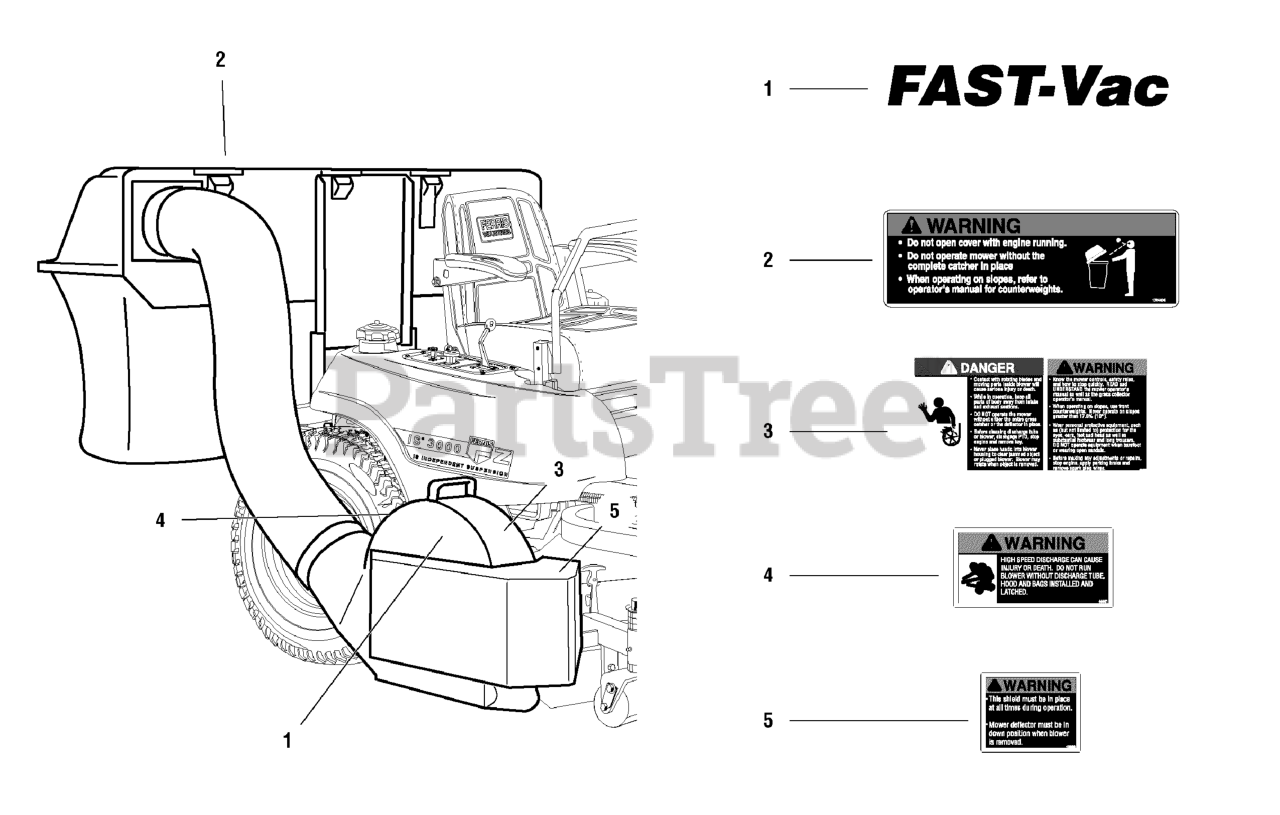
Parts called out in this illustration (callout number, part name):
1	DECAL, Fast-Vac
2	DECAL, Safety
3	DECAL, Danger/Warning
4	DECAL, Warning-Blower
5	DECAL, Warning-Shield
